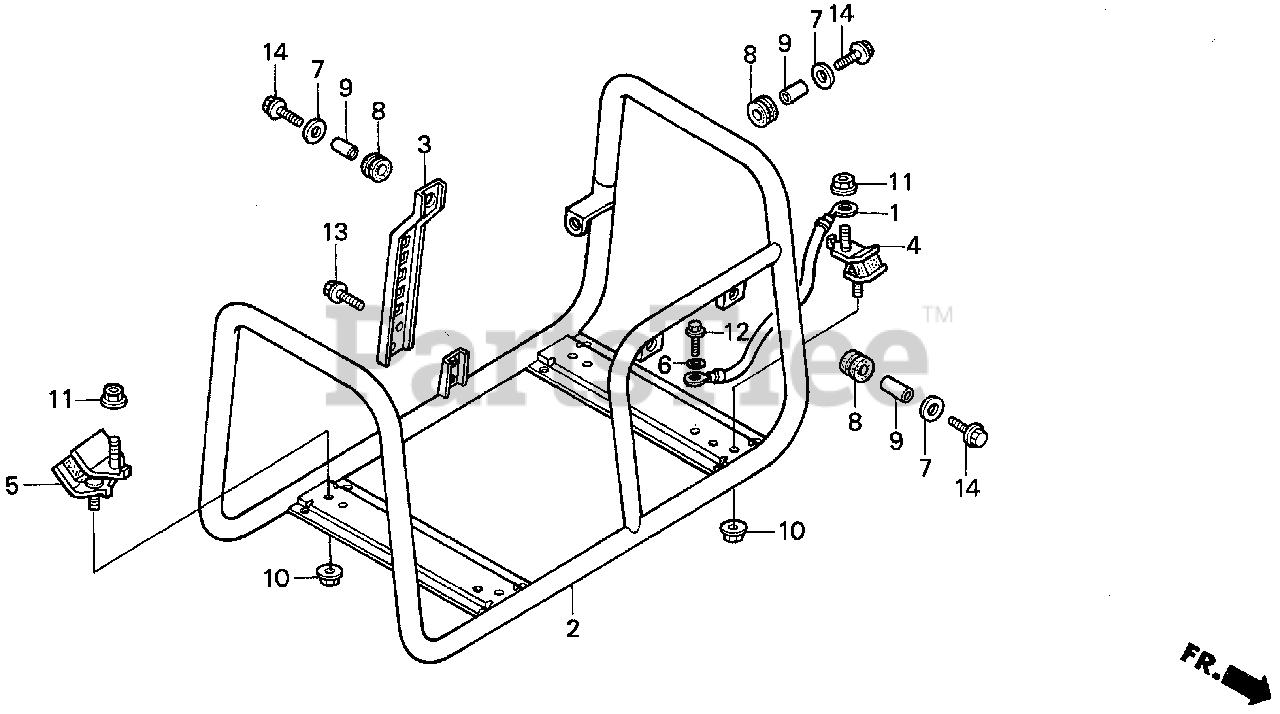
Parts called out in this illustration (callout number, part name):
1	CABLE, GROUND
2	FRAME *NH105* (MAT BLACK)
3	STAY, BOX SUPPORT
4	RUBBER (LOWER)
5	RUBBER (LOWER)
6	WASHER, LOCK (6MM)
7	WASHER, AIR DUCT
8	RUBBER, CONTROL BOX
9	COLLAR, CONTROL BOX
10	NUT, FLANGE (8MM)
11	NUT, FLANGE (10MM)
12	BOLT, FLANGE (6X10)
13	BOLT, FLANGE (6X12) Use up to Engine SN 1543277.
14	BOLT, FLANGE (6X18)
